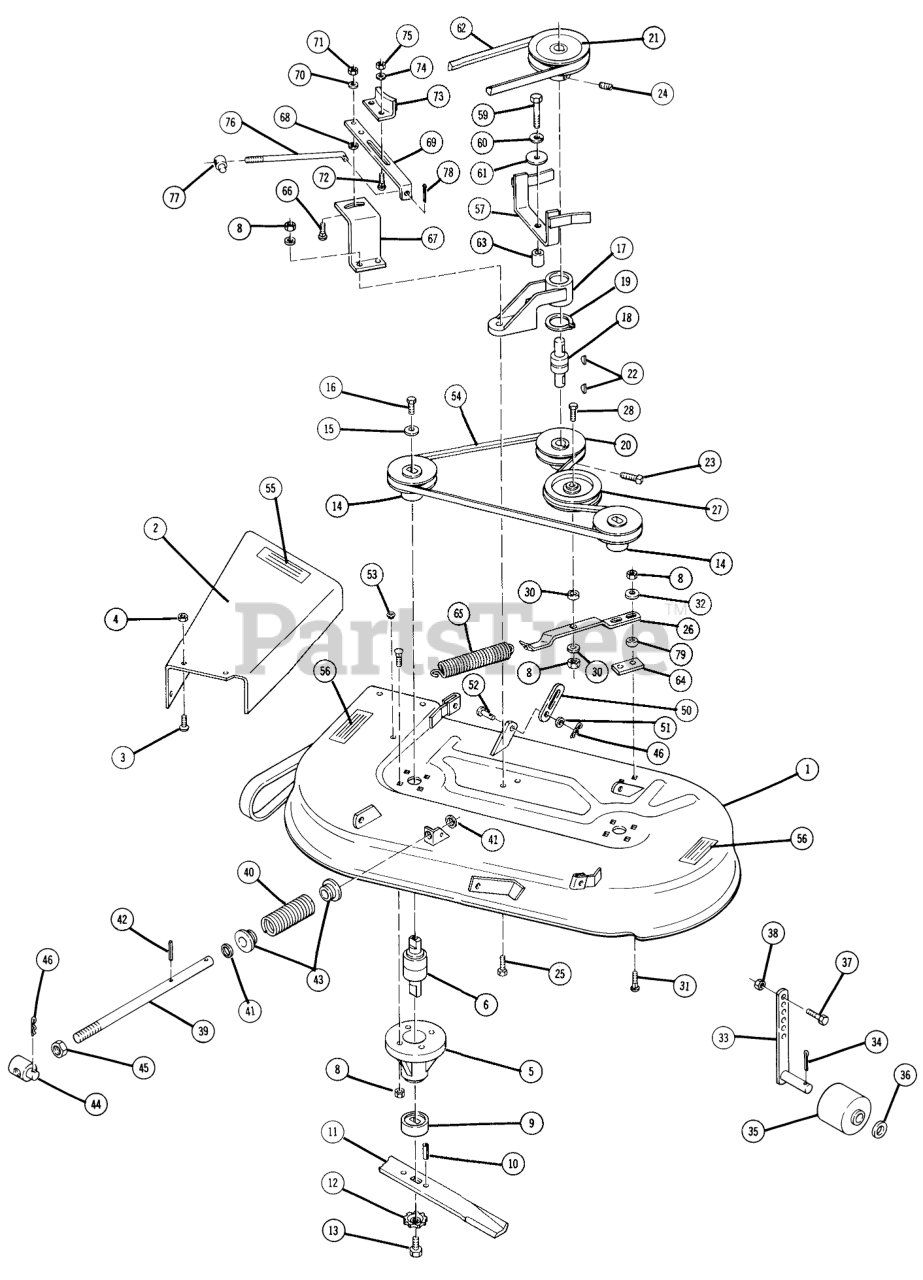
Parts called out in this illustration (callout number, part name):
2	Extension-Chute
10	SPIROL ROLL PIN
14	PULLEY
15	WASHER
20	PULLEY-LOWER DRIVE
22	Key- #9 Woodruff
32	WASHER
35	ROLLER ASSY
41	WASHER
42	SPIROL PIN
43	BUSHING
46	Hairpin Cotter
50	LIFT LINK
51	WASHER-NYLON
53	Plug Button
61	WASHER
65	SPRING-EXTENSION
68	SPACER CLUTCH ARM
69	Mower Brake Arm
73	ASSY-SUPPORT&LINING
74	WASHER 5/16 SAE
77	TRUNNION
79	SPACER
